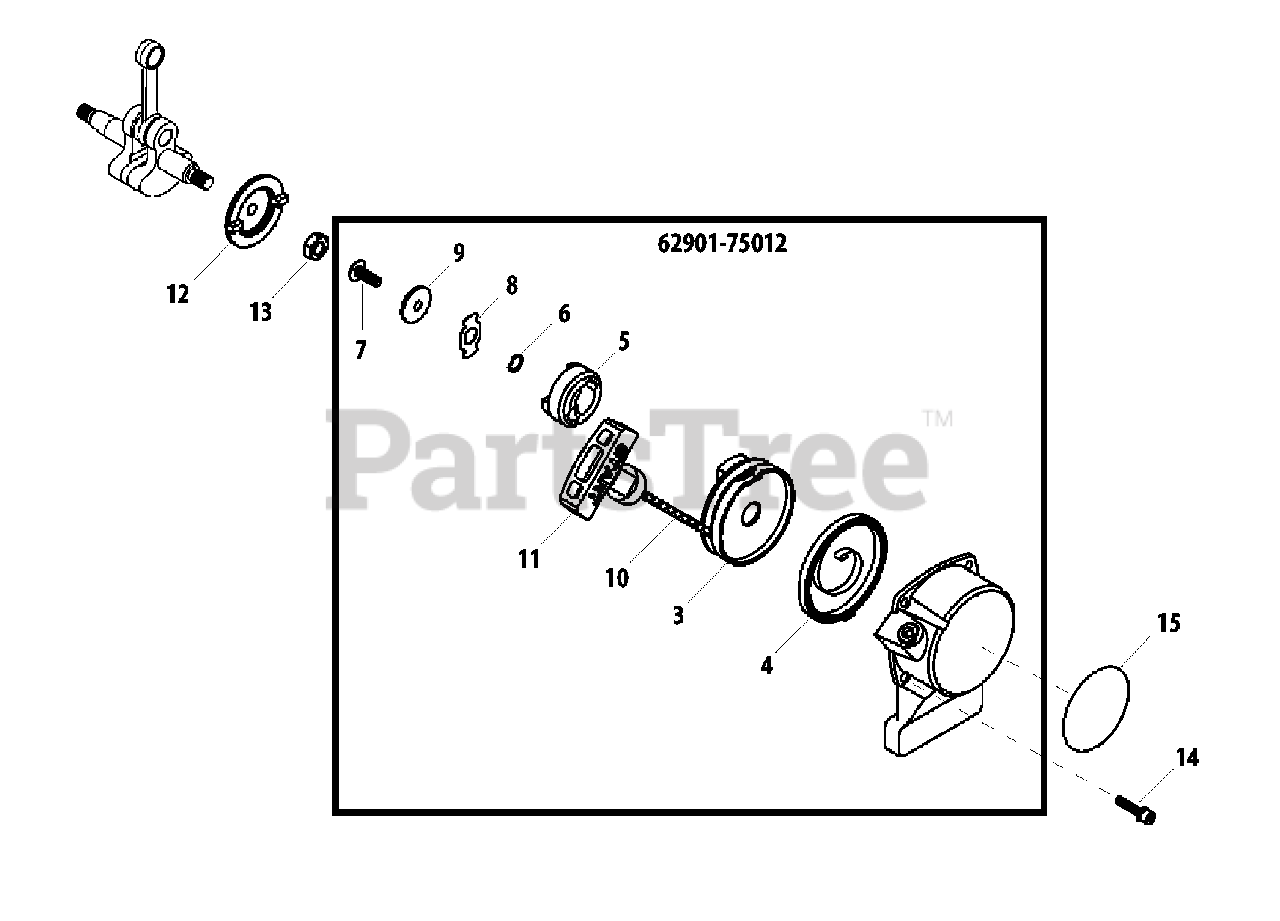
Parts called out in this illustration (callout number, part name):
3	REEL, ROPE
4	SPRING, RECOIL
5	PAWL, STARTER
6	WASHER, WAVE
7	SCREW 5 MM
8	RETAINER
9	WASHER 5 MM
10	ROPE, STARTER
11	GRIP, STARTER
12	PULLEY, STARTER
13	NUT M8×1
14	BOLT M4×16
15	LABEL, RECOIL C4
62901-75012	STARTER ASSY, RECOIL
